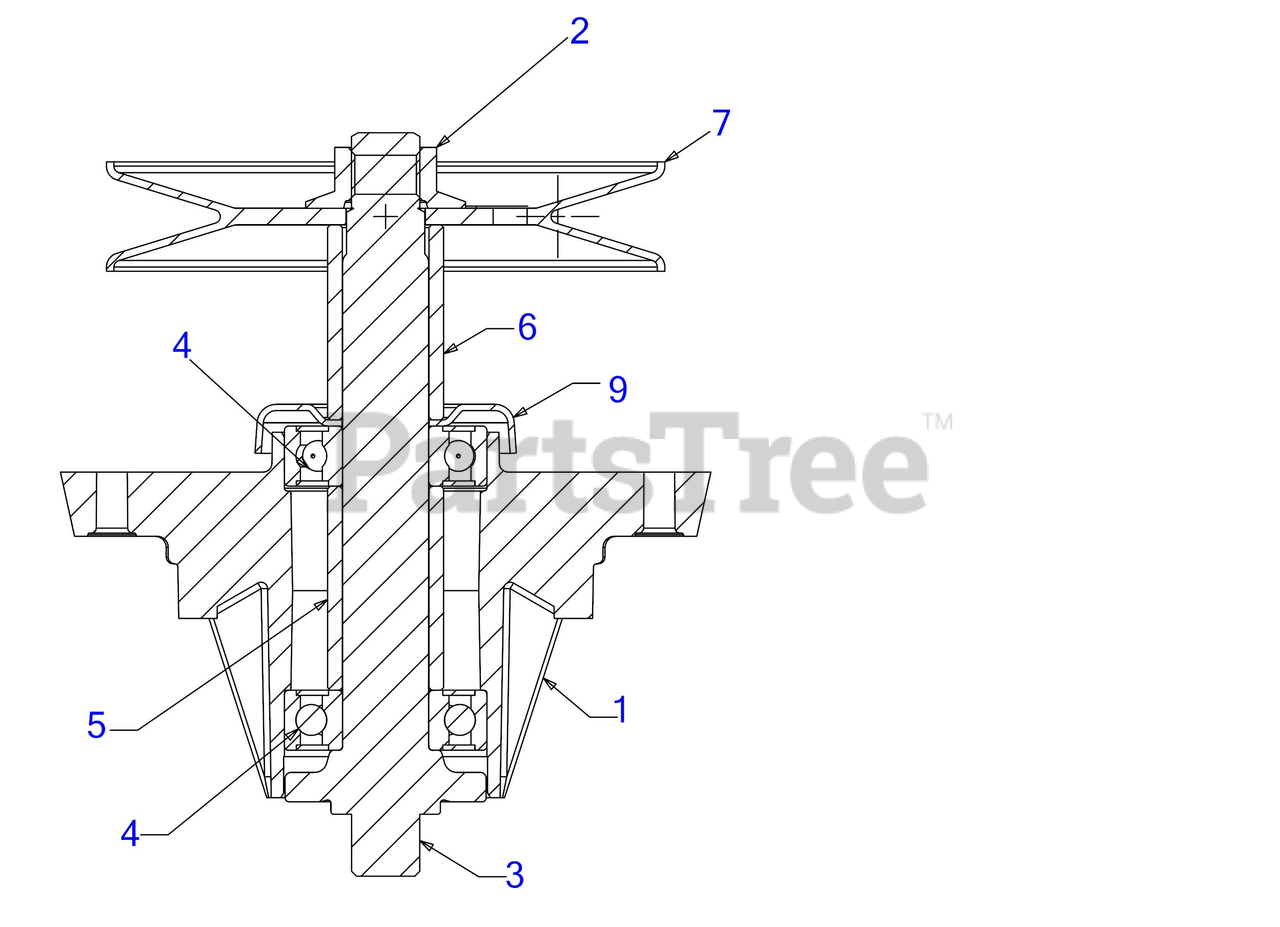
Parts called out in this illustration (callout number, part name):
1	DECK SPINDLE HOUSING
2	FLANGE NUT 5/8-18
3	BLADE SPINDLE SHAFT STAR 6.11 LG
4	BALL BEARING
5	SPACER- .792 x 1.060 x 1.860
6	SPACER .792 x 1.060 x 1.782
7	SPINDLE PULLEY 5.2 DIA
9	SHIELD-BRG DECK
